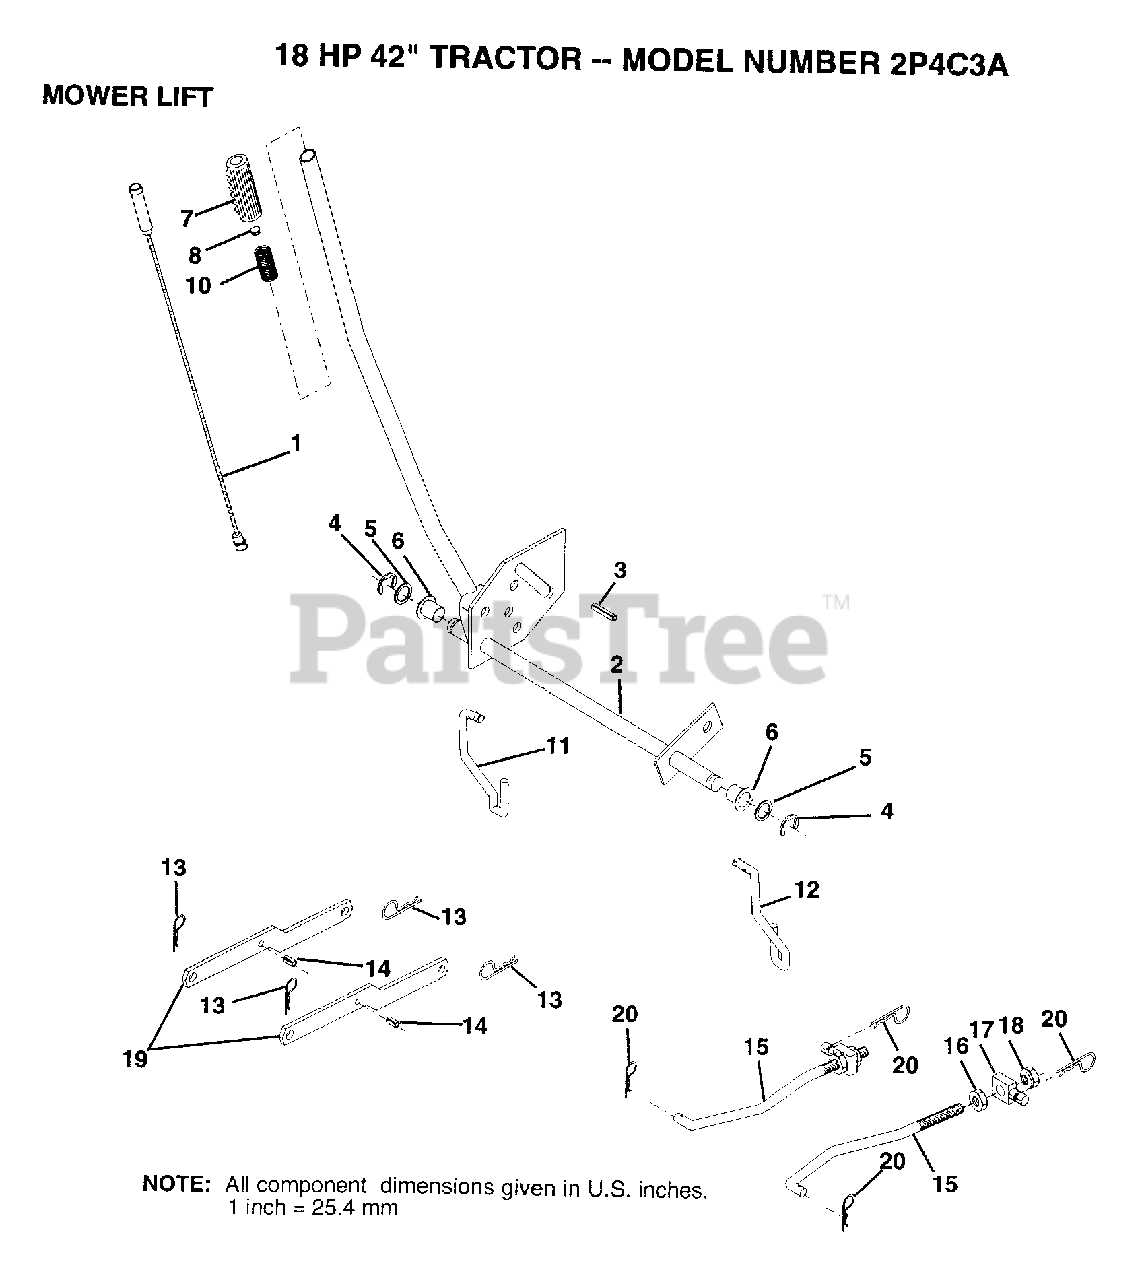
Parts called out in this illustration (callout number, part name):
1	WIRE ASM
2	SHAFT.ASM.LIFT LH
3	PIN GROOVE
5	WASHER
6	NYLON BEARING
7	GRIP
11	LINK LIFT LH
12	LIFT LINK RH
14	"PIN,SPRING"
15	LINK.FRONT
16	NUT
17	TRUNION
18	NUT.LK.W/WSH.1/2.
20	RETAINER.SPRING
